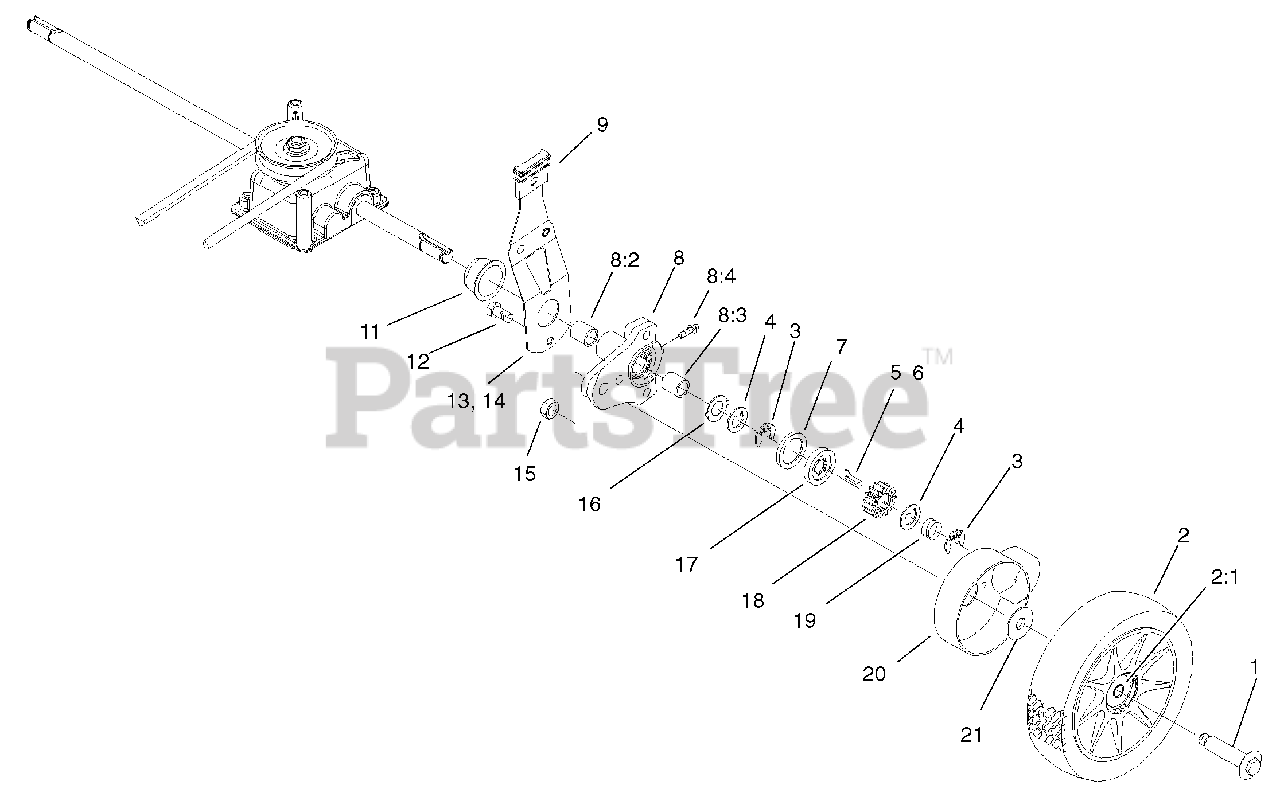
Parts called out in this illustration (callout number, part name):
1	BOLT-SHOULDER
2	WHEEL AND TIRE ASM
3	KLIPRING-LOCKING
4	WASHER-THRUST, KEYED
5	KEY-ROCKING, LH
6	KEY-ROCKING, RH
7	RING-FRICTION
8	REAR HEIGHT ADJUSTMENT ARM ASM
8:4	FITTING-GREASE
9	KNOB-LEVER, HEIGHT ADJUSTMENT
11	RING-ISOLATOR
12	SCREW-HWH
13	LH REAR SPRING ARM ASM
14	RH REAR SPRING ARM ASM
16	WASHER-ARM, PIVOT
17	WASHER-CLUTCH
18	GEAR-PINION
19	SPRING-COMPRESSION
20	COVER-WHEEL
21	WASHER-STEPPED
